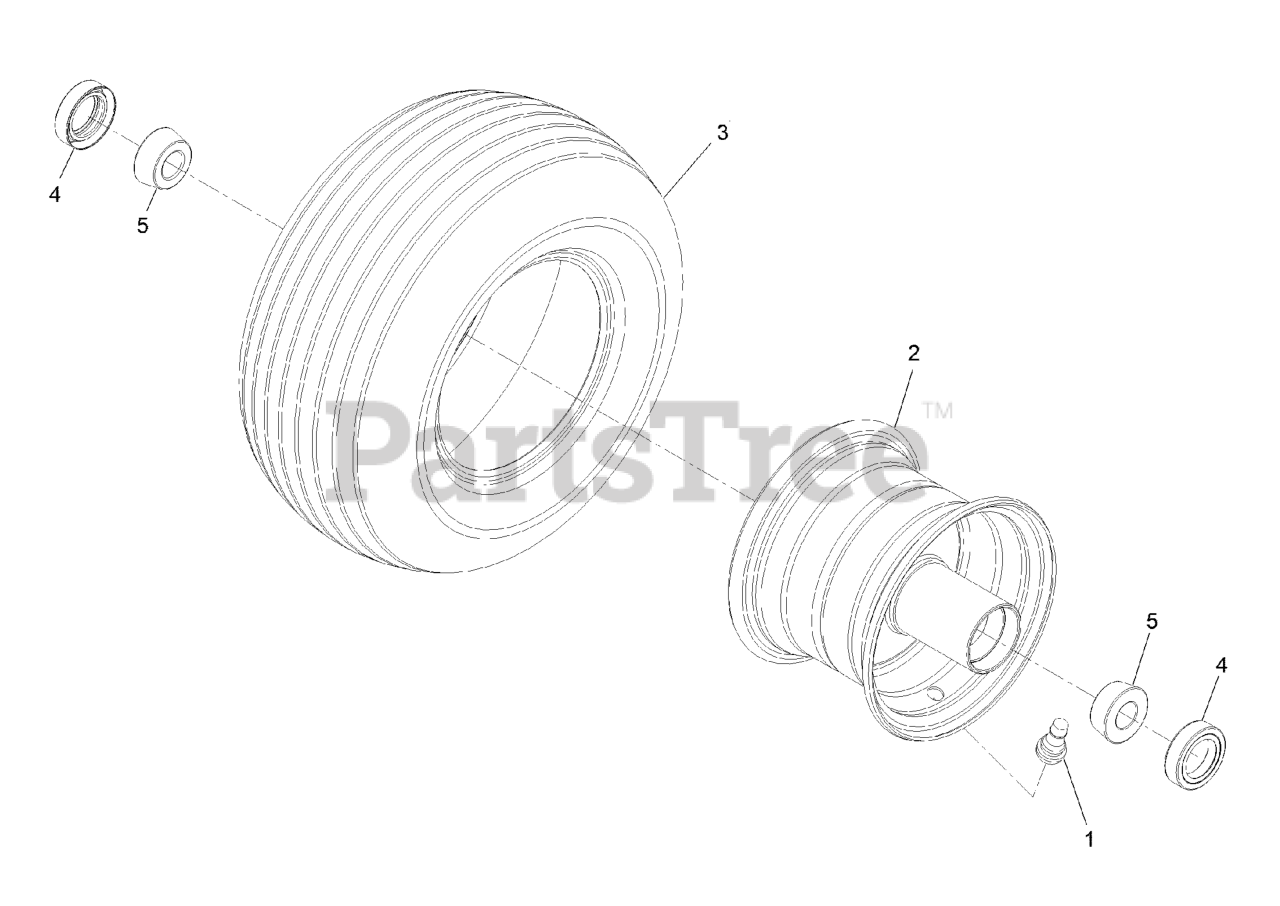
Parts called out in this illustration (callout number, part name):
1	VALVE
2	Rim-6 X 4.5
3	Tire-Rib
4	SEAL-CASTER
5	BEARING-CONE, TAPERED ROLLER
